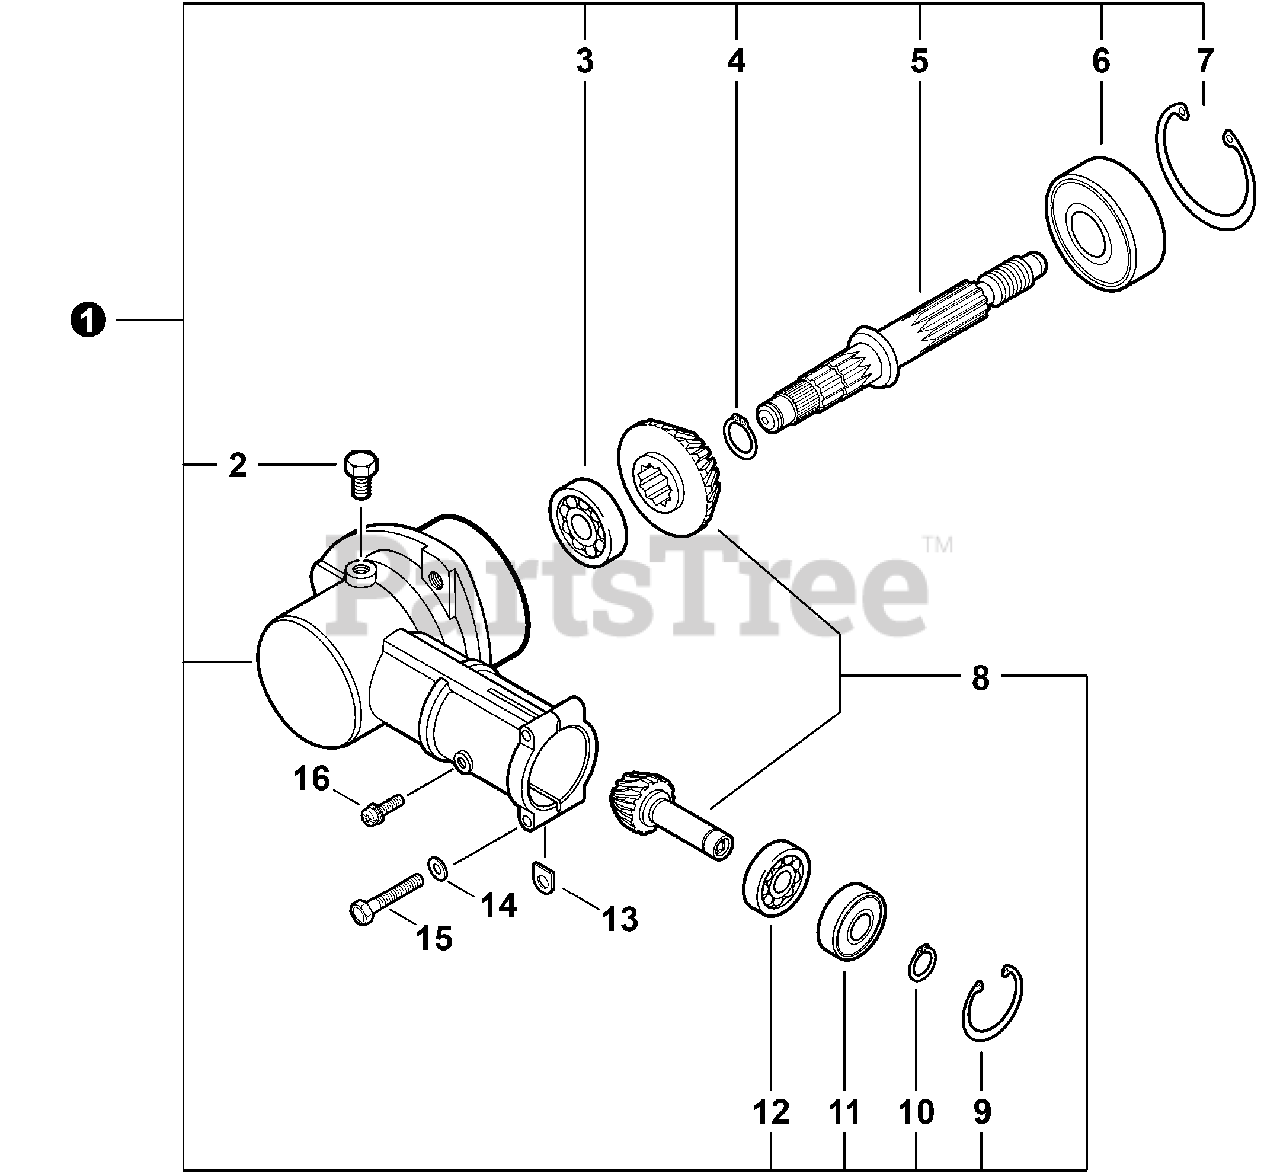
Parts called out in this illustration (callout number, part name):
1	GEAR CASE ASSY
2	BOLT M8×8
3	BEARING, BALL 629
4	RING, SNAP Ø12
5	SHAFT, GEAR
6	BEARING, BALL 6302
7	RING, SNAP Ø42
8	GEAR SET
9	RING, SNAP Ø22
10	RING, SNAP Ø10
11	BEARING, BALL 6900Z
12	BEARING, BALL 6900
14	WASHER, FLAT 5.5×10×0.8
15	BOLT 5×30
16	SCREW 5×12
